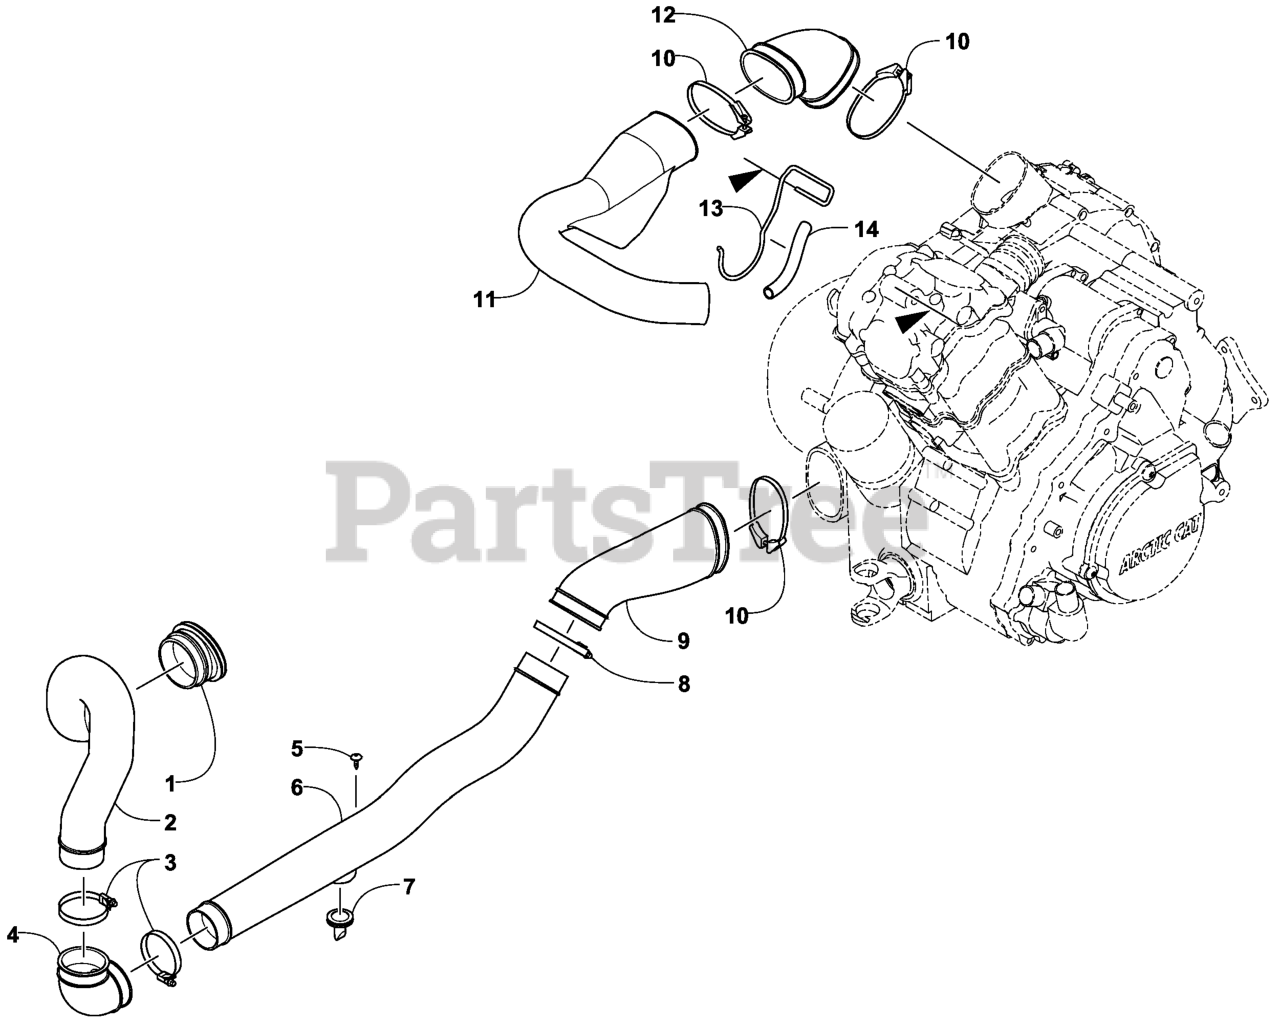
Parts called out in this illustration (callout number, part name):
1	GROMMET-CLUTCH INTAKE
2	DUCT-CLUTCH, AIR IN
3	CLAMP-WORM, HOSE
4	BOOT-AIR DUCT
5	SCREW-TSTRH, SELFTAP
6	DUCT-CLUTCH IN, #1
7	VALVE-AIR CLEANER
8	CLAMP-WORM, HOSE
9	BOOT-CLUTCH, IN
10	CLAMP-SCREW, OVAL
11	DUCT-CLUTCH, AIR OUT
12	BOOT-AIR OUT
13	SUPPORT-WIREFORM
14	HOSE-GASLINE
